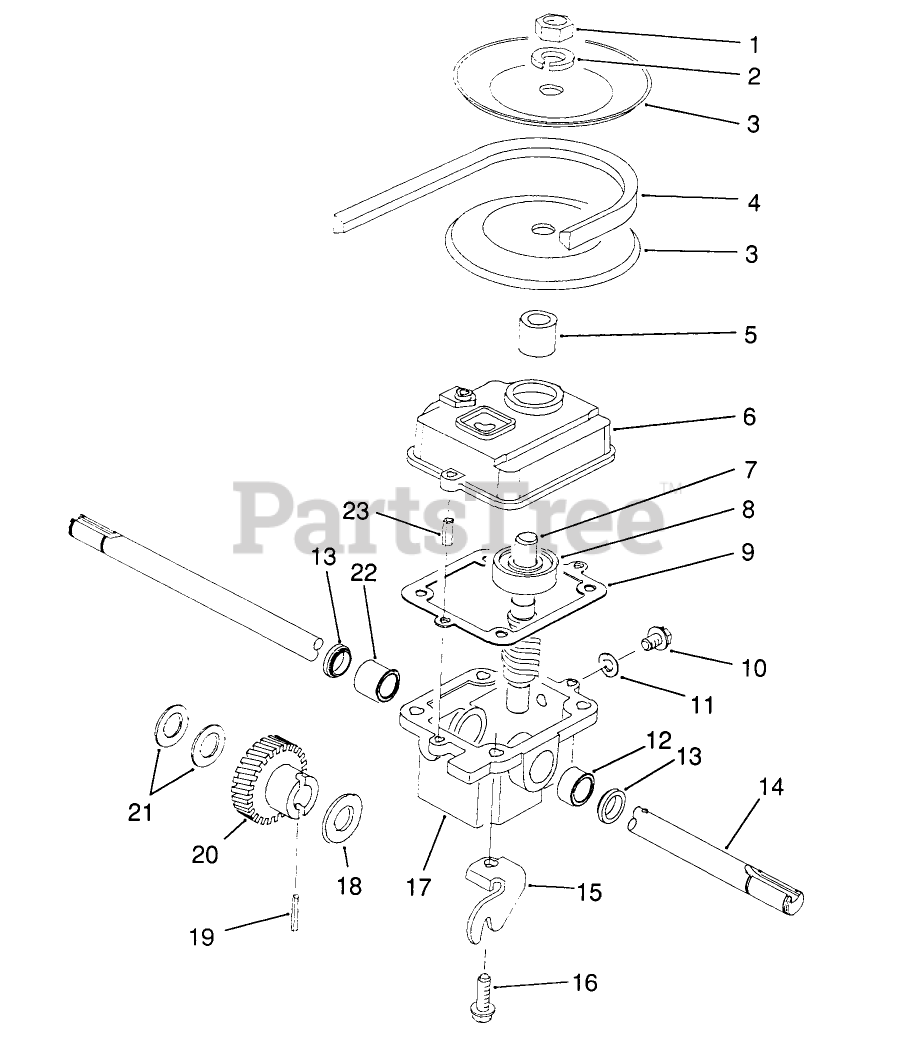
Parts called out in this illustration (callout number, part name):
1	NUT-JAM
2	WASHER-LOCK
3	PULLEY-DRIVEN HALF
4	V-BELT
5	SPACER - PULLEY
6	GEAR CASE COVER
7	SHAFT - WORM
8	BEARING
9	GASKET
10	NYLON SCREW
11	FILL PLUG GASKET
12	BUSHING
13	SEAL-OIL
14	OUTPUT SHAFT
15	TRACTION BRACKET
16	SCREW-HWHTF
17	GEAR CASE
18	THRUST WASHER
19	PIN-SPRING
20	GEAR - HELICAL
21	WASHER-PLAIN
22	BUSHING
23	3/16 X 1/2 ROLL PIN
